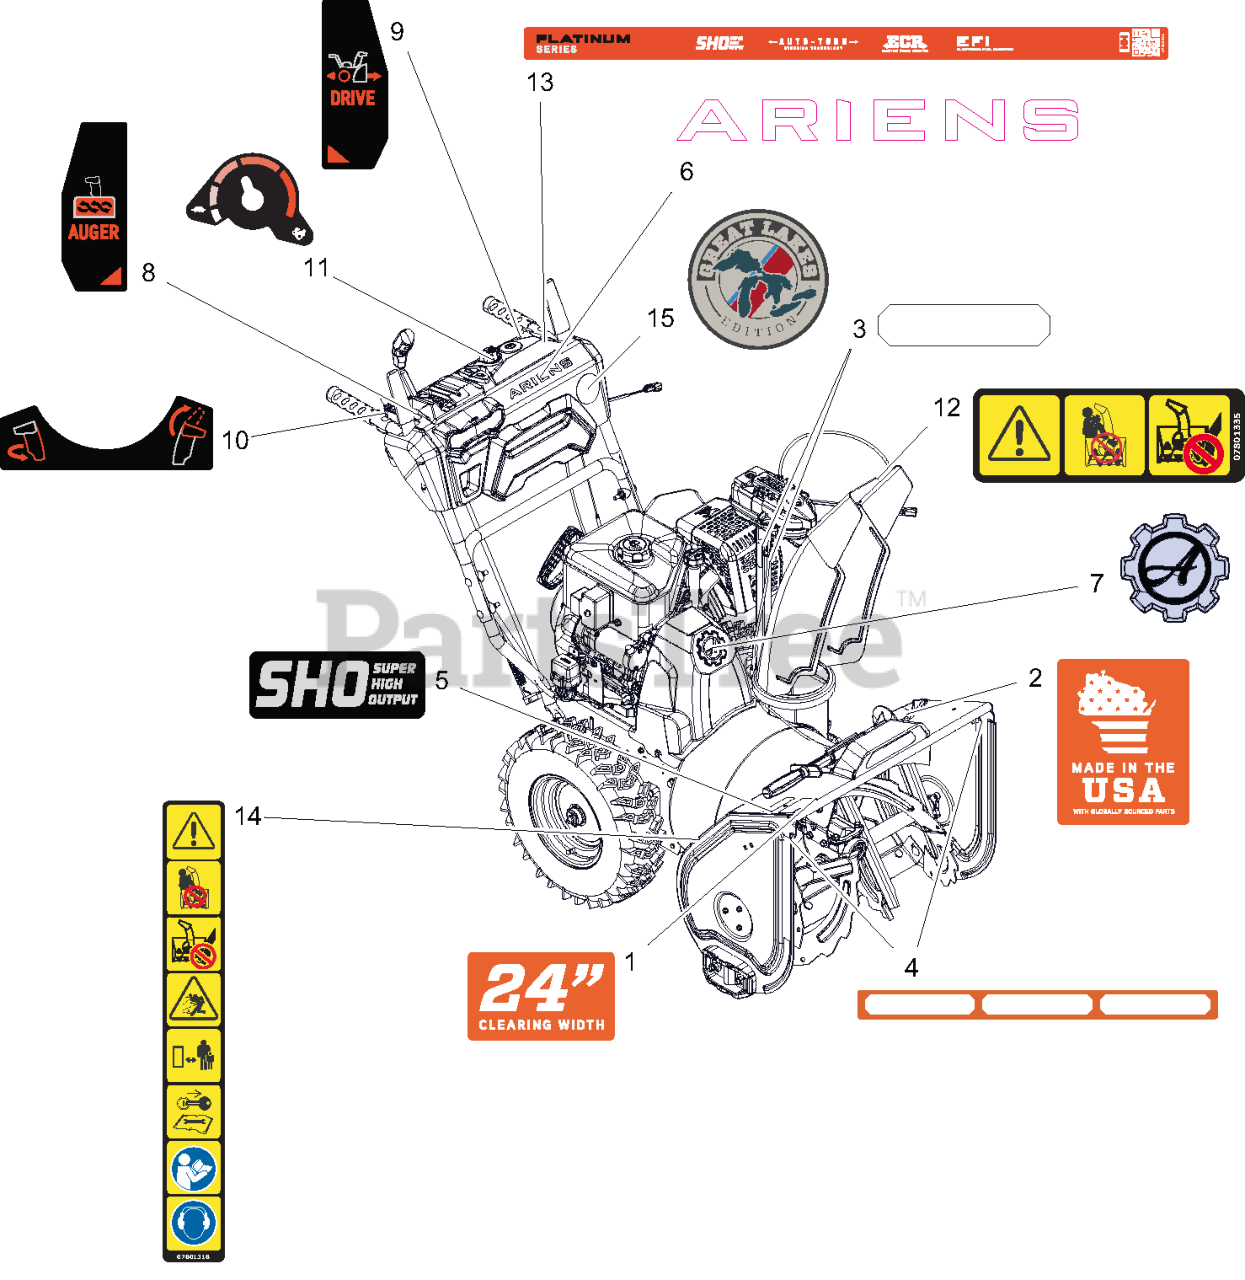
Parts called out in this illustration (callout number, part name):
1	DECAL- CLEARING - 24
2	DECAL- MADE IN USA
3	DECAL,REFLECTIVE,GEAR COVER
4	DECAL,REFLECTIVE,HOUSING
5	DECAL, SHO
6	DECAL- ARIENS - 7.46"
7	DECAL- ARIENS GEAR BADGE
8	DECAL- CONTROL - AUGER
9	DECAL- CONTROL - DRIVE WHEEL
10	DECAL- CONTORL - ECR
11	DECAL- CONTROL - EFI SPEED
12	DECAL- DANGER
13	DECAL- DASH - PLT EFI
14	DECAL- SAFETY - DANGER
15	DECAL-BADGE - GREAT LAKES
